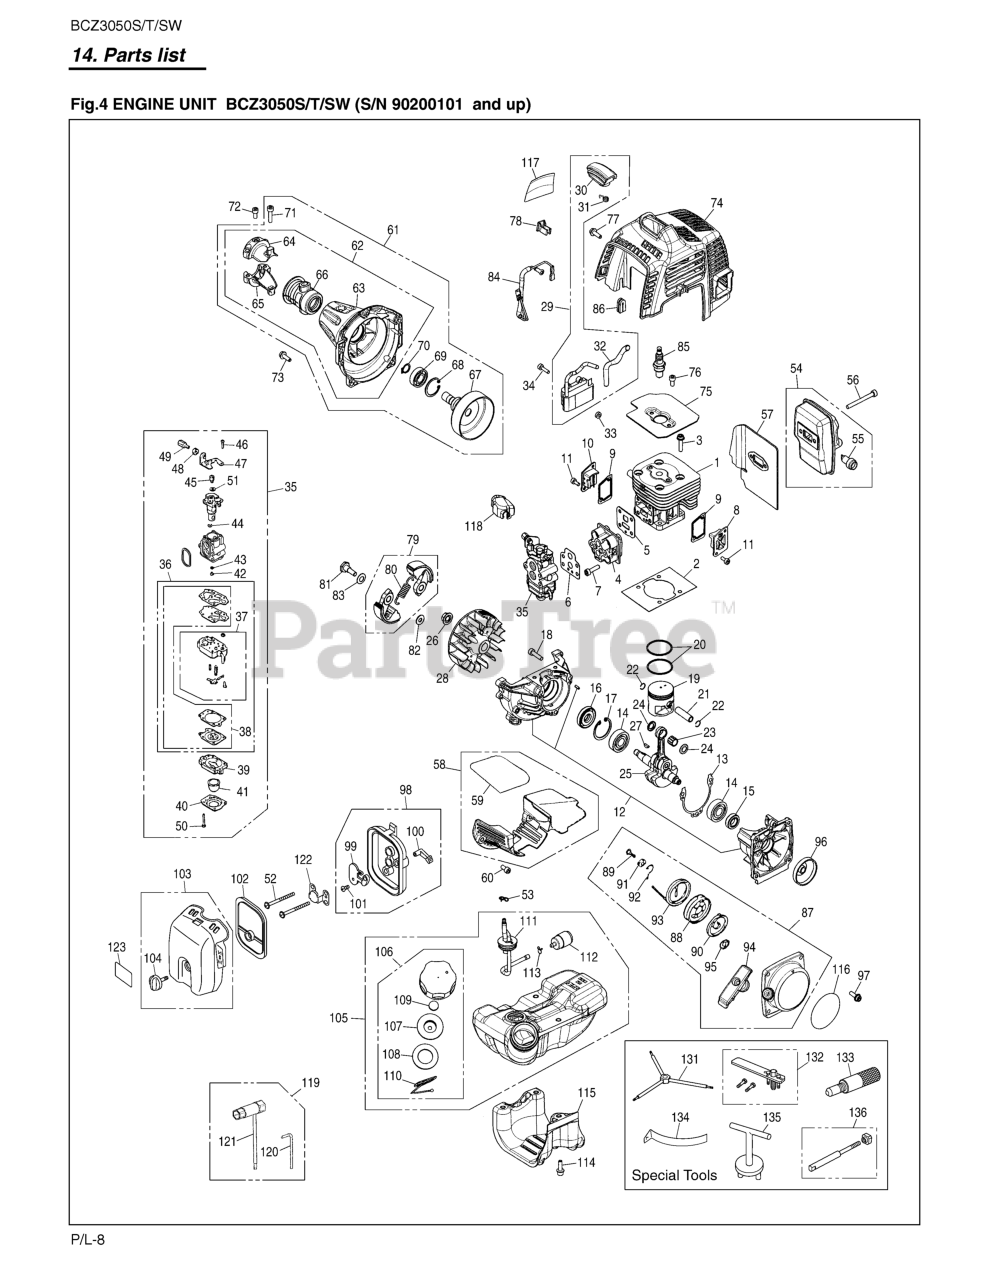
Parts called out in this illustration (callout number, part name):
2	GASKET, BASE
3	BOLT
4	INSULATOR
5	GASKET, INSULATOR
6	GASKET
7	BOLT, TORX
8	COVER, TRS
9	GASKET, TR
10	COVER, TRF
11	BOLT
12	CRANKCASE COMP
13	GASKET, CASE
14	BEARING
15	SEAL
16	SEAL
17	SNAP RING
18	BOLT TORX
20	RING
22	RING, SNAP
23	BEARING
24	WASHER
25	CRANKSHAFT COMP
26	NUT
27	KEY
28	ROTOR
29	COIL-A
30	CAP
31	SPRING
33	SPACER
34	BOLT TORX
35	CARBURETOR ASSY
36	REBUILD KIT
37	BODY ASSY
38	GASKET KIT
39	BODY, PURGE
40	COVER, PUMP
41	PUMP, PRIMING
42	JET
43	O-RING
44	RING
45	SWIVEL
46	SCREW
48	NUT
49	SCREW, CABLE ADJUSTER
50	SCREW
51	WASHER
52	BOLT TORX
53	CLIP
54	MUFFLER ASSY
55	ARRESTER
56	BOLT TORX
58	PLATE ASSY
59	SHEET
60	BOLT TORX
61	HOUSING ASSY
62	HOUSING COMP.
63	HOUSING
64	BRACKET (A)
65	BRACKET (B)
66	CUSHION
67	DRUM
68	RING
69	BEARING
70	SNAP RING
71	BOLT TORX
72	BOLT TORX
73	BOLT
74	COVER, ENGINE
75	PLATE, CYL
76	BOLT TORX
77	BOLT, TORX
78	CLAMP
79	SHOE
80	SPRING
81	SCREW
82	WASHER
83	WASHER
84	CORD COMP.
85	SPARK PLUG
86	GROMMET
87	RECOIL ASSY
88	REEL
89	SCREW
90	SPRING
91	COLLAR
92	ARM
93	ROPE
94	KNOB
95	PLATE
96	PULLEY
97	BOLT, TORX
98	CLEANER BODY ASSY
99	PLATE, CHOKE
100	LEVER
101	SCREW
102	ELEMENT
103	CLEANER COVER ASSY
104	CLEANER KNOB
105	TANK ASSY
106	CAP ASSY
107	HOLDER ASSY
108	PACKING
109	FILTER
110	STOPPER
111	PIPE COMP
112	FUEL FILTER (BLK SLEEVE)
113	CLIP
114	BOLT TORX
115	GUARD, TANK
116	LABEL, RECOIL
117	LABEL, EMISSION
118	COVER
119	TOOL SET
120	BAR
121	SOCKET
131	HEXAGON WRENCH
132	PULLER ASSY
133	STOPPER
135	PULLER
136	ROD ASSY
